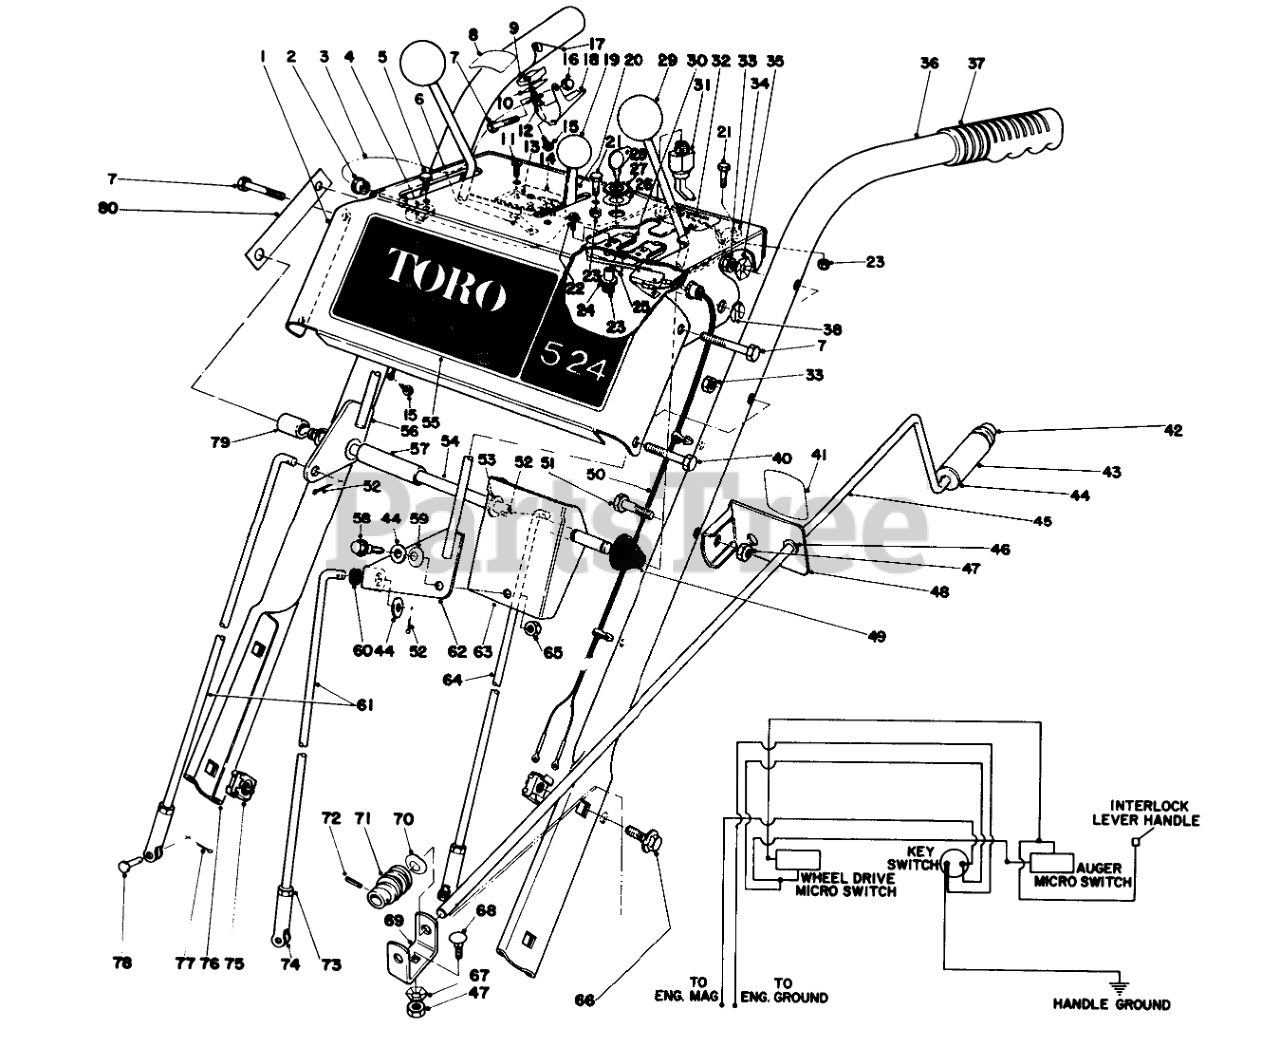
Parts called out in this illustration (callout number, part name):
1	Escutcheon
2	Snap Bushing
3	Wire Assembly
4	PLASTIC CLIP
5	SCREW
6	NUT-SPEED
7	SCREW-HH
8	INTERLOCK DECAL
9	Insulator
10	INTERLOCK CONTACT
11	SCREW-SPH
12	WASHER INSULATOR
13	MICRO SWITCH
14	SWITCH MTG PAD
15	SCREW
16	NUT-CAP
17	INTERLOCK SPRING
18	SAFETY INTRLOCK LEVER
19	CONTROL KNOB
20	Throttle Control
21	HEX HEAD SEMS 10-24X1/2
22	SCREW-SRH
23	Nut
24	INTERLOCK SPACER
25	INTERLOCK SPRING
26	WASHER-TOOTH, INTERNAL
27	NUT-HH
28	Key
30	Slide Interlock
31	SWITCH-ON / OFF
32	INSTR DECAL
33	NUT-LOCK, CONE
34	CABLE CLAMP
35	Washer
36	LEFT HANDLE
37	Grip Handle
38	RING-CLIP
40	SCREW-HH
41	CHUTE DECAL
42	RETAINER-PUSH ON
43	CHUTE CONTROL GRIP
44	WASHER-FLAT
45	CHUTE CONTROL ROD
46	Bushing
47	NUT-LOCK, NI
48	Chute Control Rod Mounting (Incl. Ref. #41 & 46)
49	CONICAL SPRING
50	Wire Harness Interlock
51	SCREW-HH
52	PIN-COTTER
53	WASHER-FLAT
54	PIVOT ROD
55	ESCUTCHEON DECAL
56	LEVER WA
57	SHIFT LEVER SPACER
58	SHOULDER SCREW
59	7/16 SPRING WASHER
60	GROMMET-RUBBER
61	SPEED SELECTOR ROD
62	SHIFT LEVER WA
63	SHIFT BRACKET
64	TRACTION CONTROL ROD
65	NUT-LOCK, CONE
66	SCREW-HHF
67	WASHER-LOCK
68	BOLT-CARR
69	WORM BRACKET
70	WASHER-SPRING
71	GEAR-WORM, CHUTE
72	PIN-SPRING
73	NUT-HJ
74	CLEVIS
75	Retained Nut
76	RIGHT HANDLE
77	PIN-COTTER
78	PIN-CLEVIS
79	AUGER LEVER SPACER
80	ESCUTCHEON SUPT STRAP
